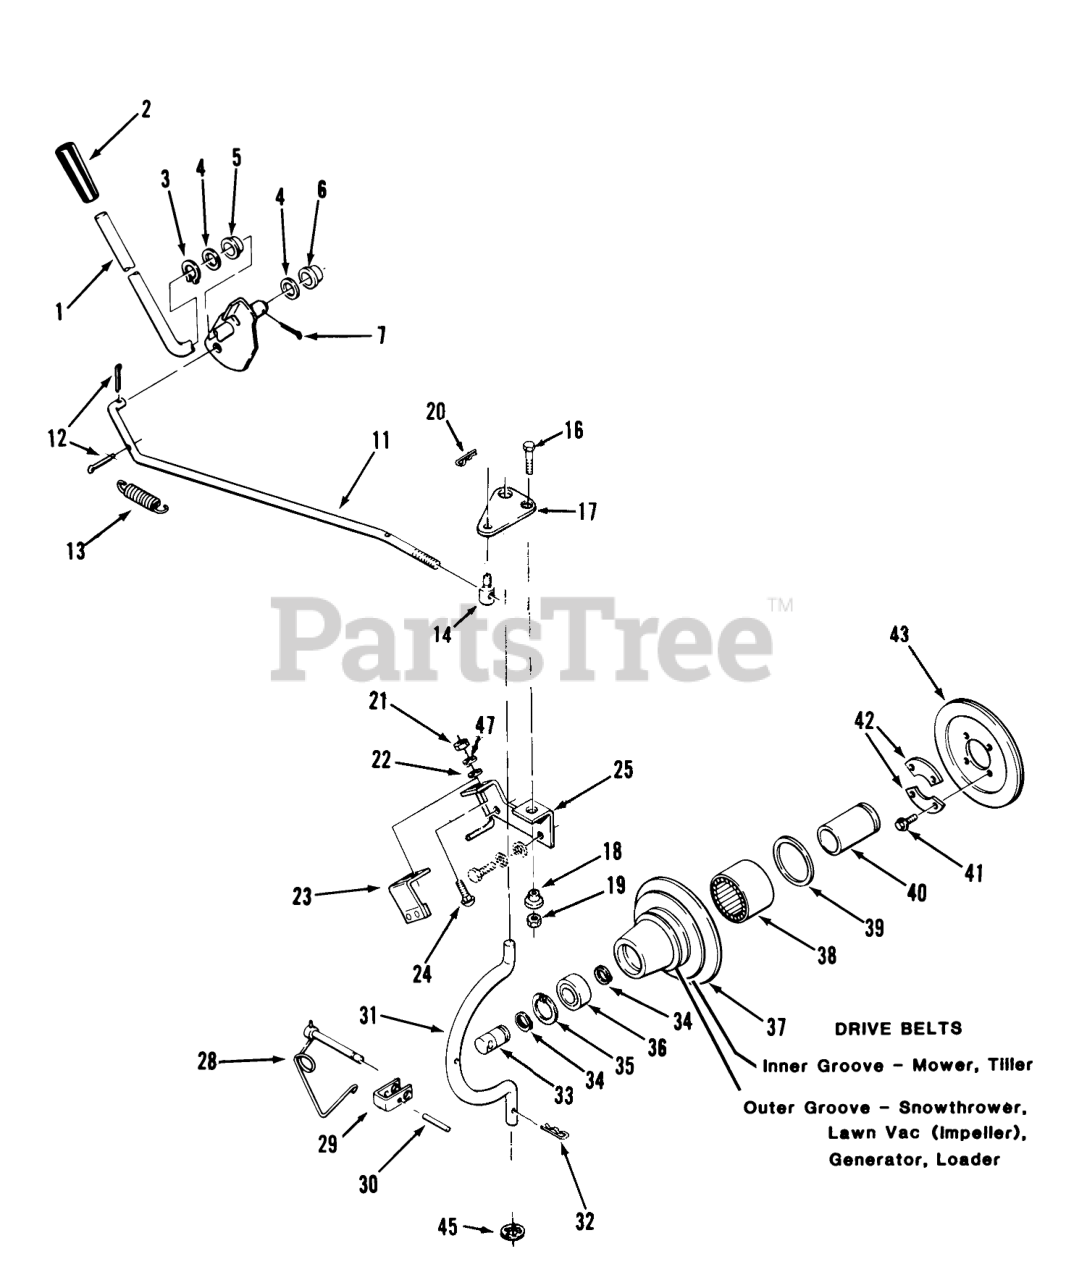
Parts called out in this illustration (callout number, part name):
1	ASSY PTO CLUTCH LEVE
2	GRIP
3	Grip Ring
4	SHIM-WASHER
5	BUSHING-NYLINER
6	NYLINER BUSHING
7	Pop Rivet
11	ROD-PTO CLUTCH
12	Pop Rivet
13	SPRING
14	TRUNNION
16	Bolt
17	PLATE
18	SPACER-LIFT LINK
19	NUT
20	Hairpin Cotter
21	Nut
23	ASM-Bracket
24	Bolt-Carriage
25	ASS'Y-ENGINE BRKT B
25	Bracket-Engine
28	LOCKING PIN ASM
29	CLEVIS
31	ROD-HOUSING
32	Hairpin
33	SHAFT-PTO
34	RING-SNAP, EXTERNAL
35	Ring-Snap
36	BEARING-BALL
37	Housing-Clutch
38	BRG-NEEDLE OPEN END
39	SEAL-OIL
40	RACE-BEARING
41	H H C S
42	RETAINER
43	Facing-Clutch
45	RING-REINFORCED CIRC
47	Washer
